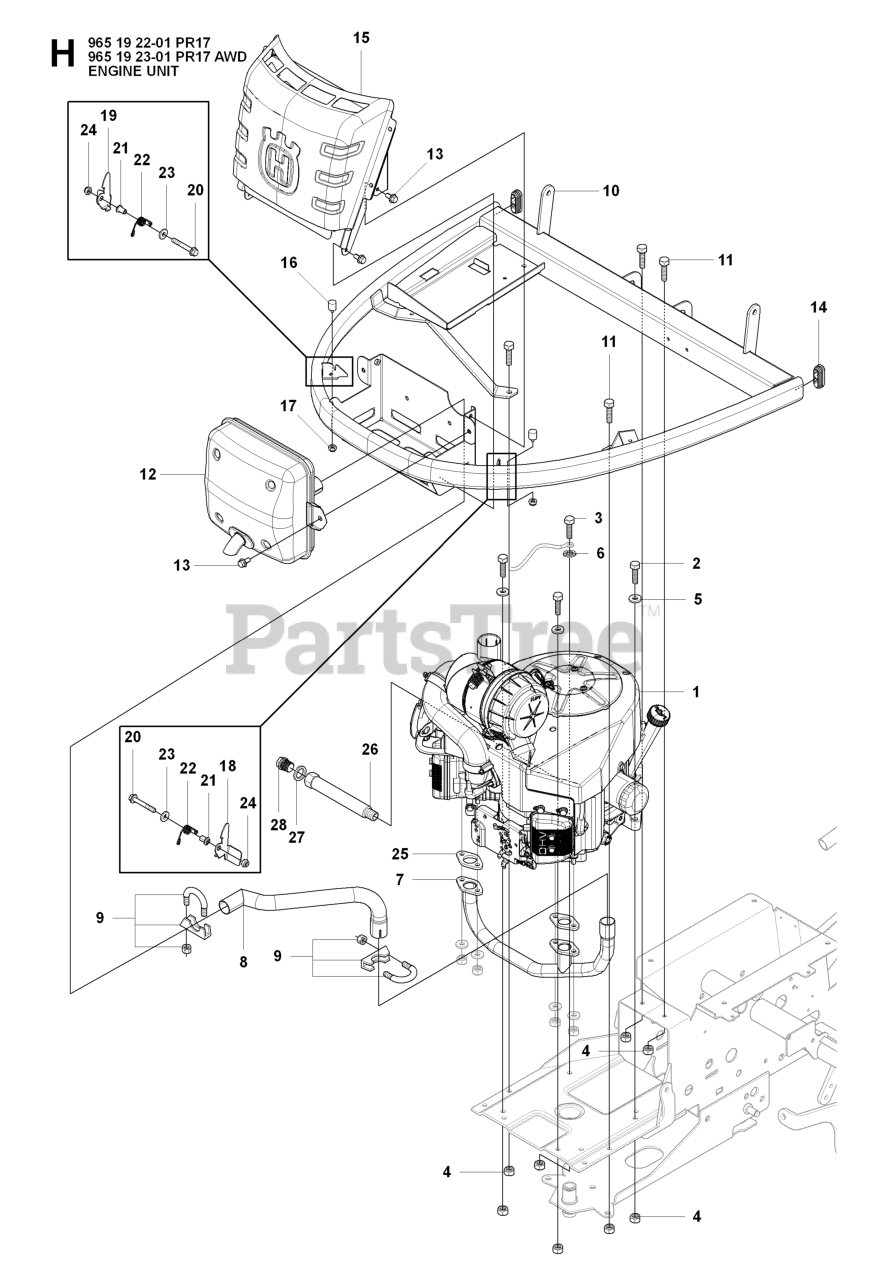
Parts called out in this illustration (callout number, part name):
4	LOCKNUT M8
5	WASHER BRB 8.4X17
9	CLAMP
13	SCREW EHHFM
17	LOCKNUT M5
23	WASHER - 26X6.5X1.6
24	LOCKNUT M6
